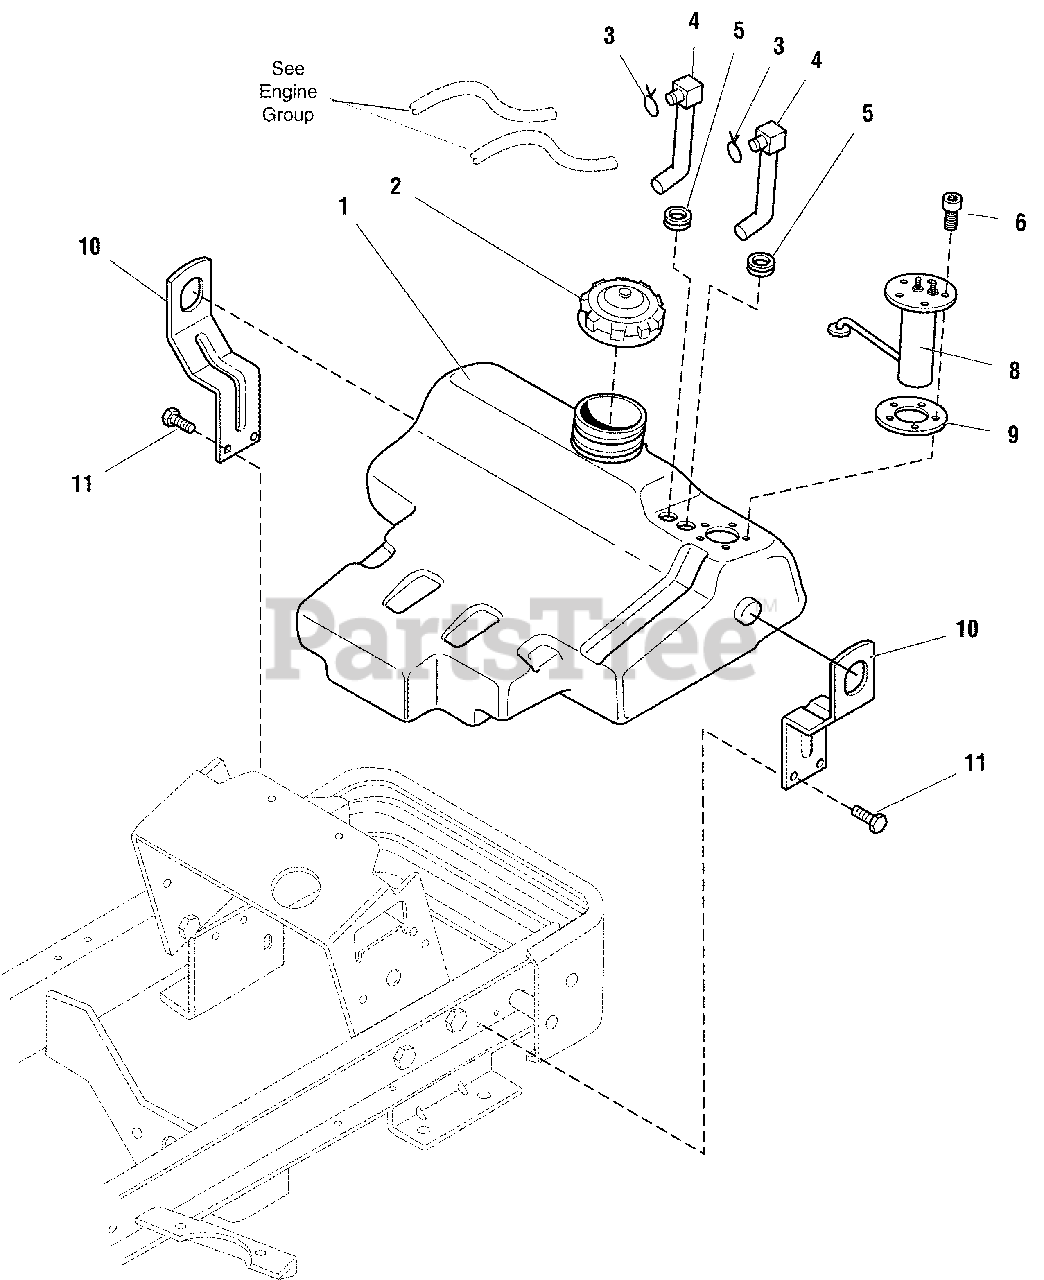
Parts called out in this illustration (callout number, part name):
2	CAP, Fuel Tank, Labeled "Diesel Fuel Only"
3	CLAMP, Hose
4	ELBOW, Fuel Tank
5	BUSHING, Fuel Tank Seal
6	SCREW-SEMS TORX PAN HD #10-32 x 1/2
8	SENDER, Fuel Level
9	GASKET, Fuel Tank
10	SUPPORT, Fuel Tank
11	CAPSCREW, Hex Hd, Taptite, 5/16-18 x 3/4
